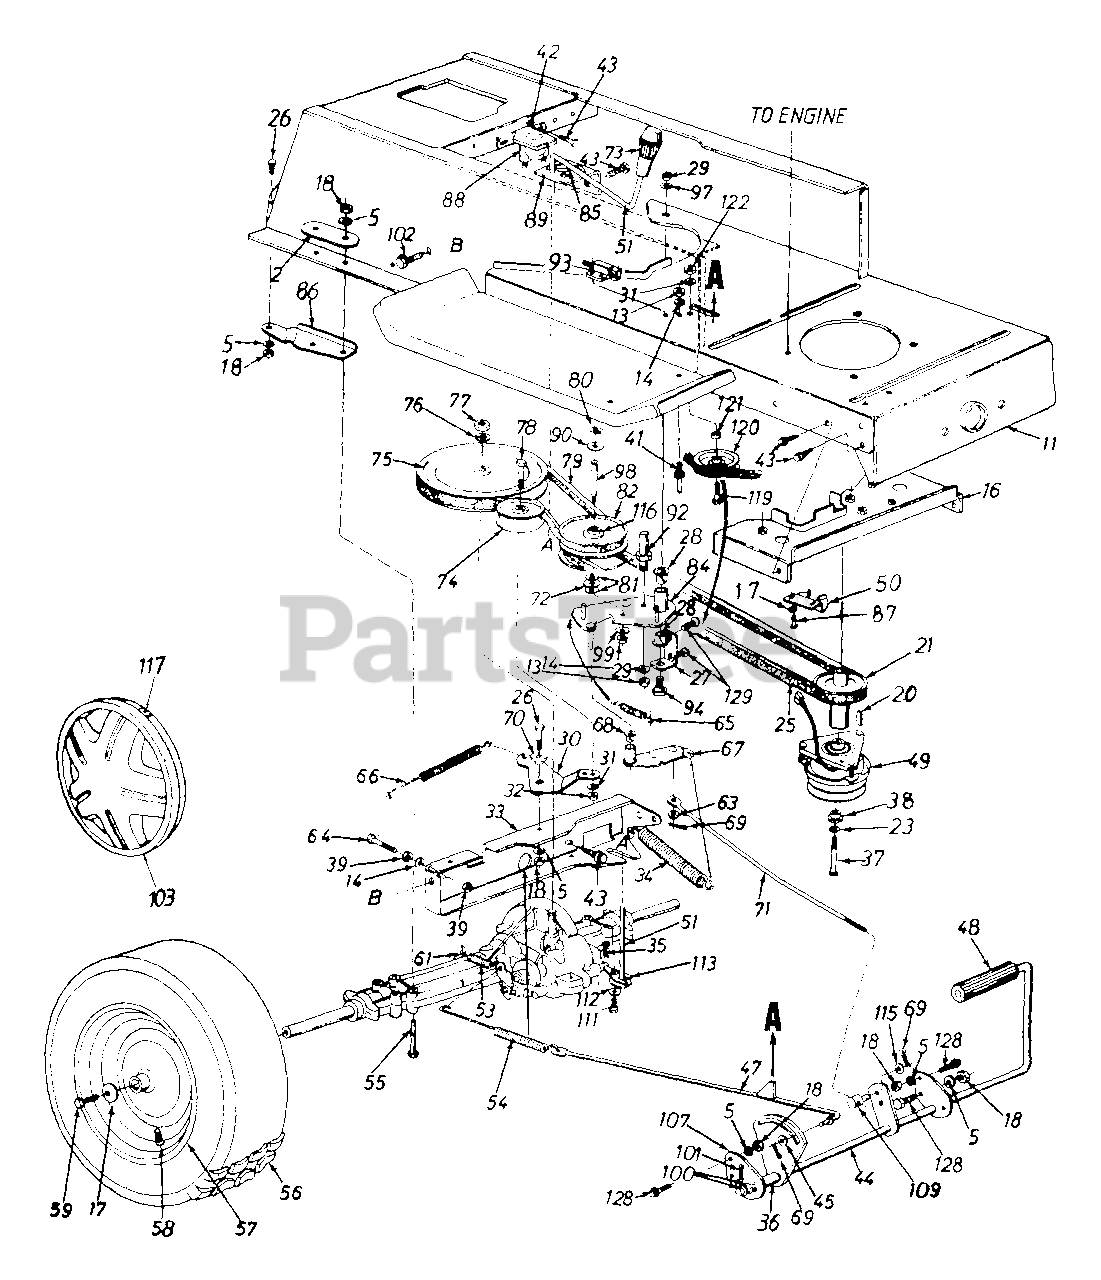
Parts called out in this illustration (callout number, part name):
5	L-Wash. 5/16" I.D.
14	L-Wash. 1/4" I.D.
18	Hex Nut 5/16-18 Thd.
20	Sq. Key 1/4" x 1.5"
21	Engine Pulley
23	L-Wash. 7/16" I.D.
25	Variable-Speed Belt
26	Hex Bolt 5/16-18 x .75" Lg.
27	Bearing Shaft Bracket Ass'y.
28	Flanged Nyliner Brg. 5/8" I.D. x .88" Lg.
29	Hex Nut 3/8-24 Thd.
31	L-Wash. 3/8" I.D.
32	Hex Nut 3/8-24 Thd.
35	Inter. Cotter Pin
36	Spacer .63" I.D.
37	Hex Bolt 7/16-20 x 3.25" Lg.
38	Shld. Spacer .445" I.D.
39	Hex Nut 1/4-28 Thd.
41	Belt Guard Pin
42	Ext. L-Wash. 1/4" I.D.
43	Hex Wash. Hd. S-Tap Scr. 1/4-20 x .50" Lg.
47	Brake Rod Ass'y.
48	Foot Pad
49	Electric Clutch
53	Ext. Spring .38" O.D. x 2.5"
54	Ext. Spring .59" O.D. x 7.08" Lg.
55	Hex Bolt 5/16-18 x 3" Lg.
58	Air Valve
59	Hex Bolt 5/16-24 x .75" Lg.
61	Brake Return Spring Anchor
63	Fl-Wash. .34" I.D. x .68" O.D.
64	Hex Bolt 1/4-28 x 1.25" Lg.
65	Ext. Spring
66	Ext. Spring .62" O.D. x 6.12"
68	Flanged Bearing
69	Cotter Pin 3/32" Dia.
70	Shoulder Spacer .27" Lg.
71	Speed Control Link
72	Truss Bearing .56 Dia. x 1.25"
73	Shift Knob
74	Fl-Idler Pulley 3.25" x .75"
75	"V" Pulley
76	Bell-Wash. .56" I.D. x 1.125"
77	Hex Jam Nut 5/16-18 Thd.
78	Hex Bolt 3/8-24 x 1.75" Lg.
79	Variable Speed Belt
80	Snap Ring .56" Dia.
82	Variable Speed Pulley Ass'y. 5" O.D.
88	Solenoid
90	Teflon Washer .565" I.D.
92	Belt Keeper 3" Lg.
93	Safety Switch (Clutch)
94	Shld. Bolt 3/8-24 x 3.12" Lg.
97	Bell-Wash. .38" I.D. x .88"
98	Shaft .56" Dia. x 3.875" Lg.
99	Bell-Wash. .39" I.D. x 1.12"
100	Fl-Wash. .64" I.D. x .94"
101	Cotter Pin 1/8" Dia. x 1.25"
102	Hex Wash. Hd. Scr. 5/16-18 x .62" Lg.
111	Hex Bolt 1/4-28 x .50" Lg.
112	Bell-Wash. .265" I.D. x .75"
113	Shift Lever Link Ass'y.
115	Fl-Wash. .385" I.D. x .62"
116	Needle Brgs.
117	Spring Clip
119	Hex Bolt 3/8-16 x 1.25" Lg.
120	Fl-Idler w/Flanges 2.75" O.D.
121	Fl-Wash. .39" I.D. x 1.12" O.D.
122	Hex Nut 3/8-16 Thd.
128	Hex Wash. TT-Tap Scr. 5/16-18 x .75" Lg.
129	Hex Wash. AB-Tap Scr. 5/16-18 x .75" Lg.
